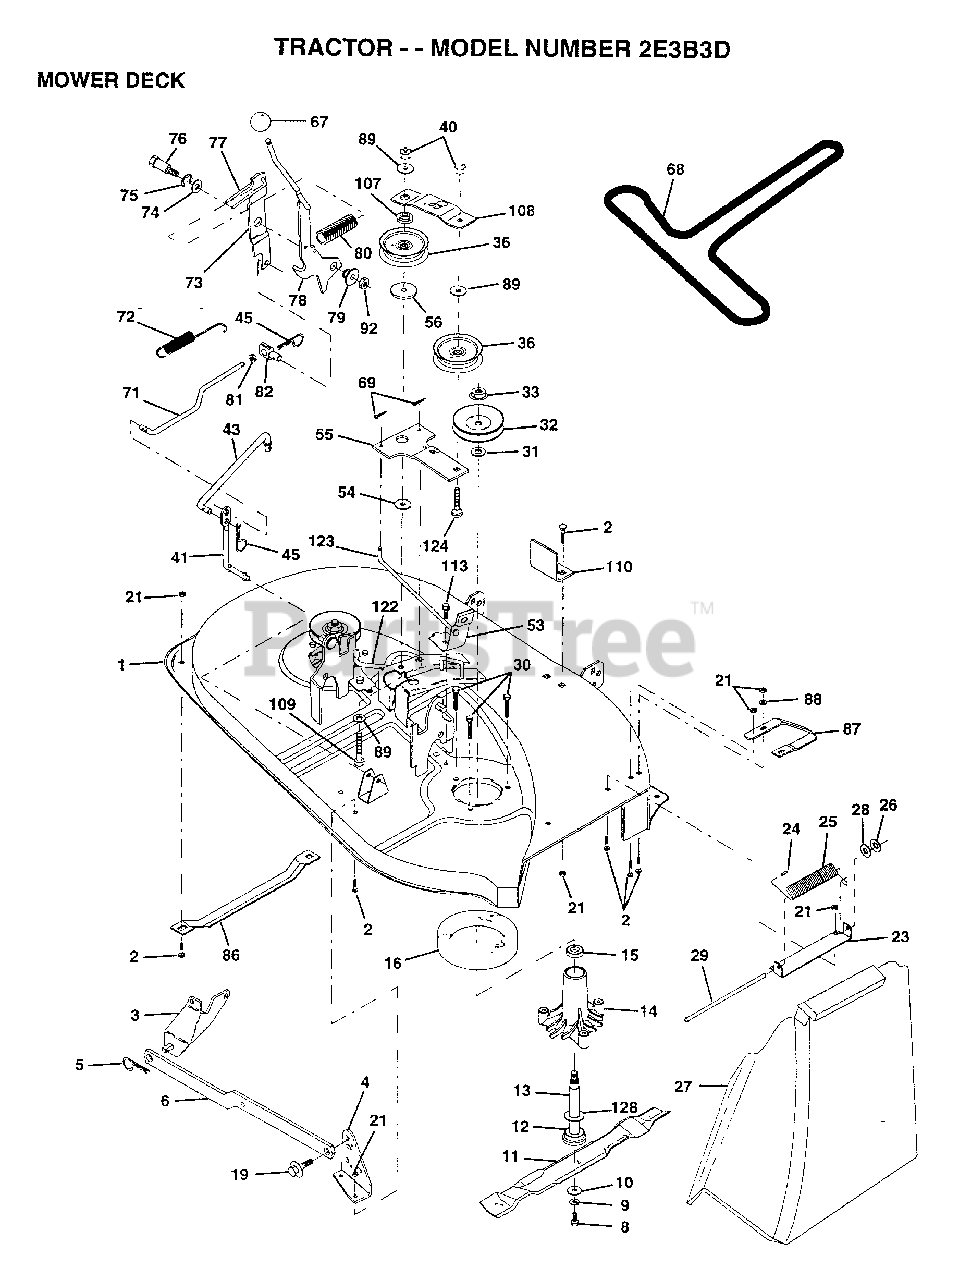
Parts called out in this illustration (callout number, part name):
2	BOLT
3	BRKT ASM SWAY BAR
4	BRKT DECK SW BAR
8	BLADE BOLT
10	WASHER.HARD.BLADE
11	"BLADE.38"" HIPERF"
12	BEARING.BALL
14	HSG ASM MANDREL
15	BEARING
16	STRIPPER RND MWR
19	BOLT SHD 5/16-18
23	BRKT DEFLECTOR
24	CAP-SLEEVE LT
25	SPRING TORSION
26	NUT PUSH M
27	DEFLECTOR-SHLD T
28	WASHER
29	ROD-HINGE T
31	WASHER
32	PULLEY.MANDREL.38
36	FLAT IDLER PULLEY
41	PIVOT ROD
43	CLUTCH ROD SECOND
45	RETAINER M
53	BRAKE ASM
54	HARDENED WASHER
55	IDLER ARM ASSY
56	SPACER RETAINER
67	KNOB T(3/8 HOLE)
68	BELT.V.T-PATH
71	ROD CLUTCH 38/42
72	RETURN SPRING
73	CLUTCH ARM SECOND
74	WASHER
75	RING
76	SHOULDER BOLT
77	SPRING KEEPER
79	BUSHING
80	SPRING.CLUTCH.MWR
81	NUT
82	TRUNION ADJ
86	RUNNER-LH M
87	RUNNER RH
88	WASHER M
89	WASHER GT
92	NUT
107	RETAINER SPACER
108	IDLER ARM STIFF
109	BOLT
110	UPSTOP DECK FT 38
113	SCREW
122	BRAKE ROD LH
123	BRAKE ROD RH
124	BOLT
128	WASHER.FELT.
